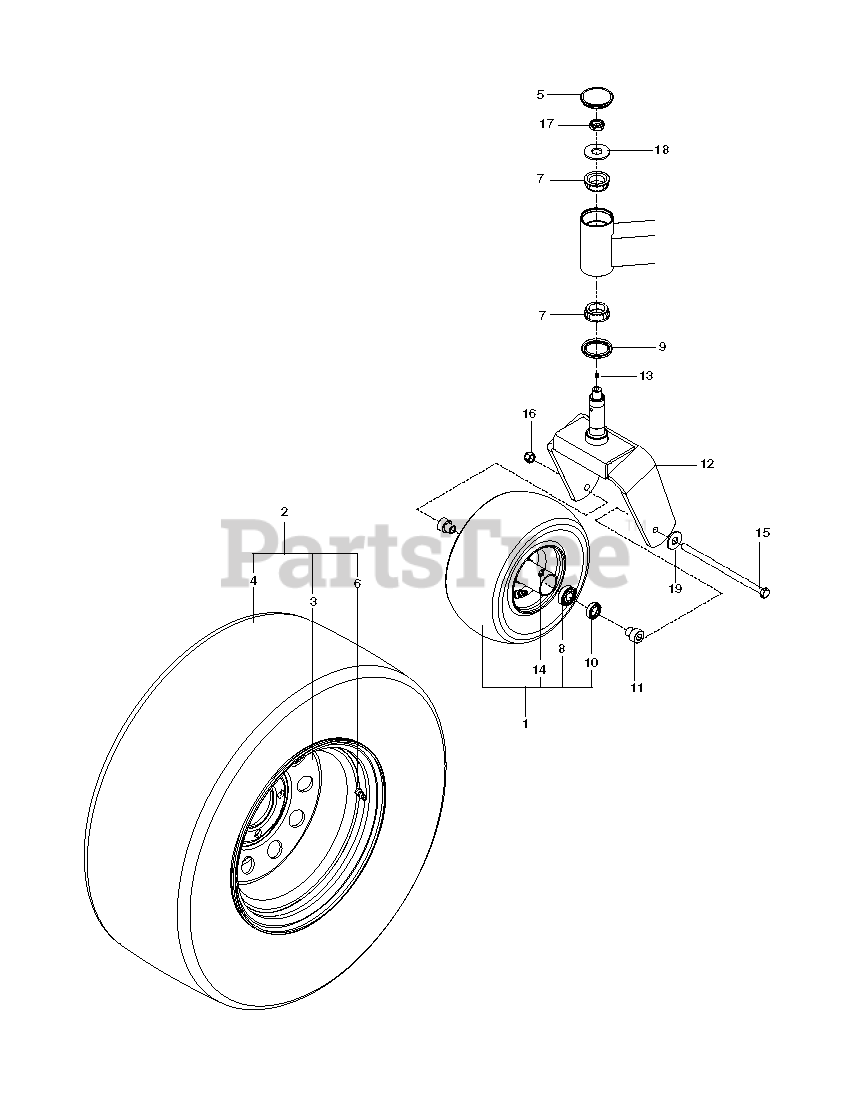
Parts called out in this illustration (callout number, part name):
1	TIRE, 13 X 6.5-6 NO FLAT
2	WHEEL/TIRE.ASM SILV 23X10.5-12
3	RIM, 12 X 8.5, 1.125" NEG OS
4	TIRE.TURF.MASTER.23X10.5-12
6	VALVE STEM TR-412
7	CONE, LM67048
8	TAPERED BEARING W/RACE
9	SEAL, BEARING
11	AXLE SPACER
12	FORK.CASTER.ORANGE
13	ZERK
14	ZERK
15	HEX SCREW 1/2-13 X 9.5 GR5
16	NUT, 1/2-13 HEX FLG NYLOC ZD
17	NUT, 3/4-16 HEX THIN NYLOC ZD
18	WASHER, 3/4 HARDENED
19	WASHER 1/2" FLAT
